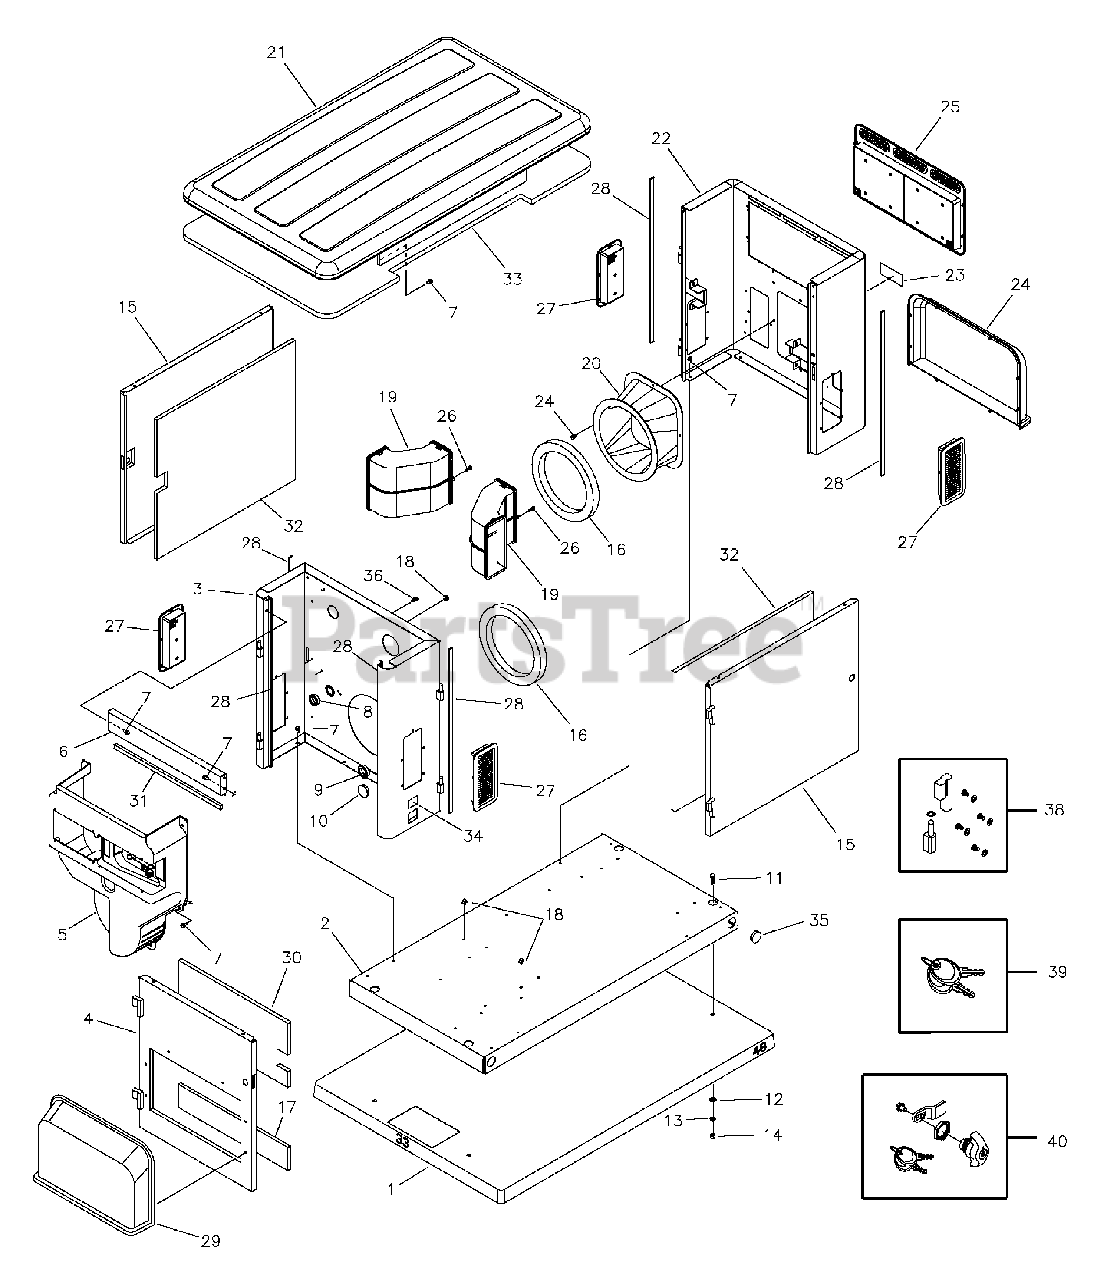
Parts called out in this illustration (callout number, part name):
1	PAD, Mounting w/ Holes
2	BASE, Mounting
3	BULKHEAD, Engine
4	ASSEMBLY, Door, Engine End
7	BOLT
9	BUSHING, Snap, 1-1/2
11	* CAPSCREW, Hex Head, 3/8-16 x 1
12	* WASHER, Flat, 3/8-M10
13	* WASHER, Lock, 3/8
14	* NUT, 3/8-16
16	SEAL, Foam
17	INSULATION, Engine Door, Bottom
18	MOUNT, Tie Wrap
20	ADAPTER, Engine
22	BULKHEAD, Alternator
24	COVER, Air Intake
25	ASSEMBLY, Vent, Exhaust
29	COVER, Air Intake, Engine
30	INSULATION, Engine Door, Top
34	DECAL
